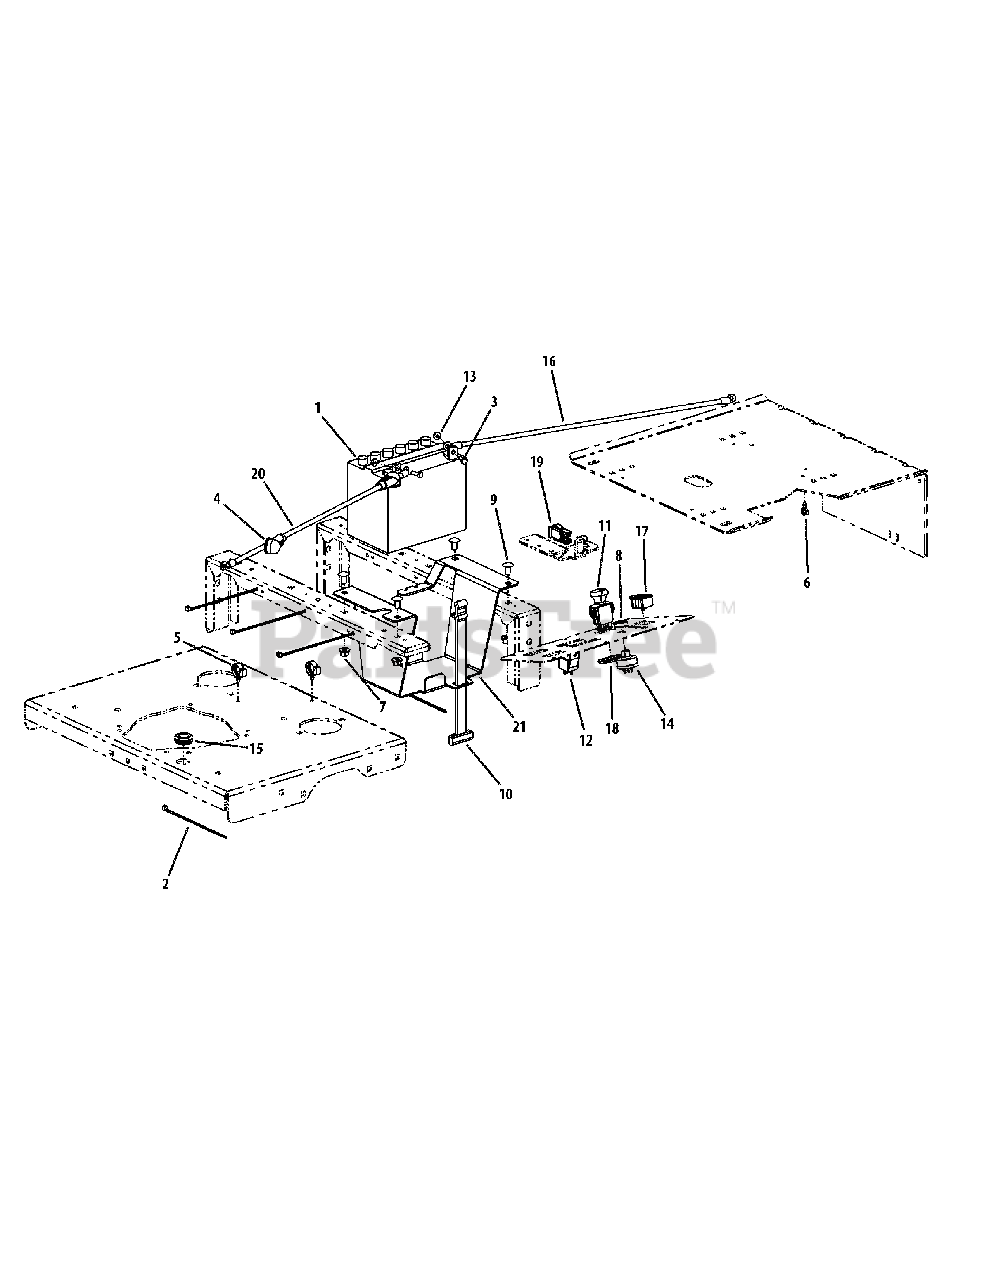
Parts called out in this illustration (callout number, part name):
1	Battery, 12V 225CCA 30 Min
2	Tie, Cable, 3/16 x .05 x 7.4"
3	Screw, Hex, Cap, 1/4-20 x .75
4	Boot, 1" OD Rubber Battery-PST, Red
5	Electrical Conduit Clip, 5/8
6	Electrical Conduit Clip, 3/8
7	Flange Lock, Hex Nut, 3/8-16
8	Nut, W/Cap, 5/8-32 Ignition
9	Carriage Bolt, 3/8-16 x .75 Long
10	Strap, Battery
11	Switch, Electric, PTO
12	Relay, 12V 40A
13	Lock Nut, 1/4-20
14	Switch, Ignition, 6 Pin
15	Grommet, .75 ID
16	Cable, Battery Red, 34"
17	Meter, Hour
18	Bracket, PTO Switch Retainer
19	Switch, Safety N.O./N.C.
20	Cable, Battery, Red, 42"
21	Battery Bracket
